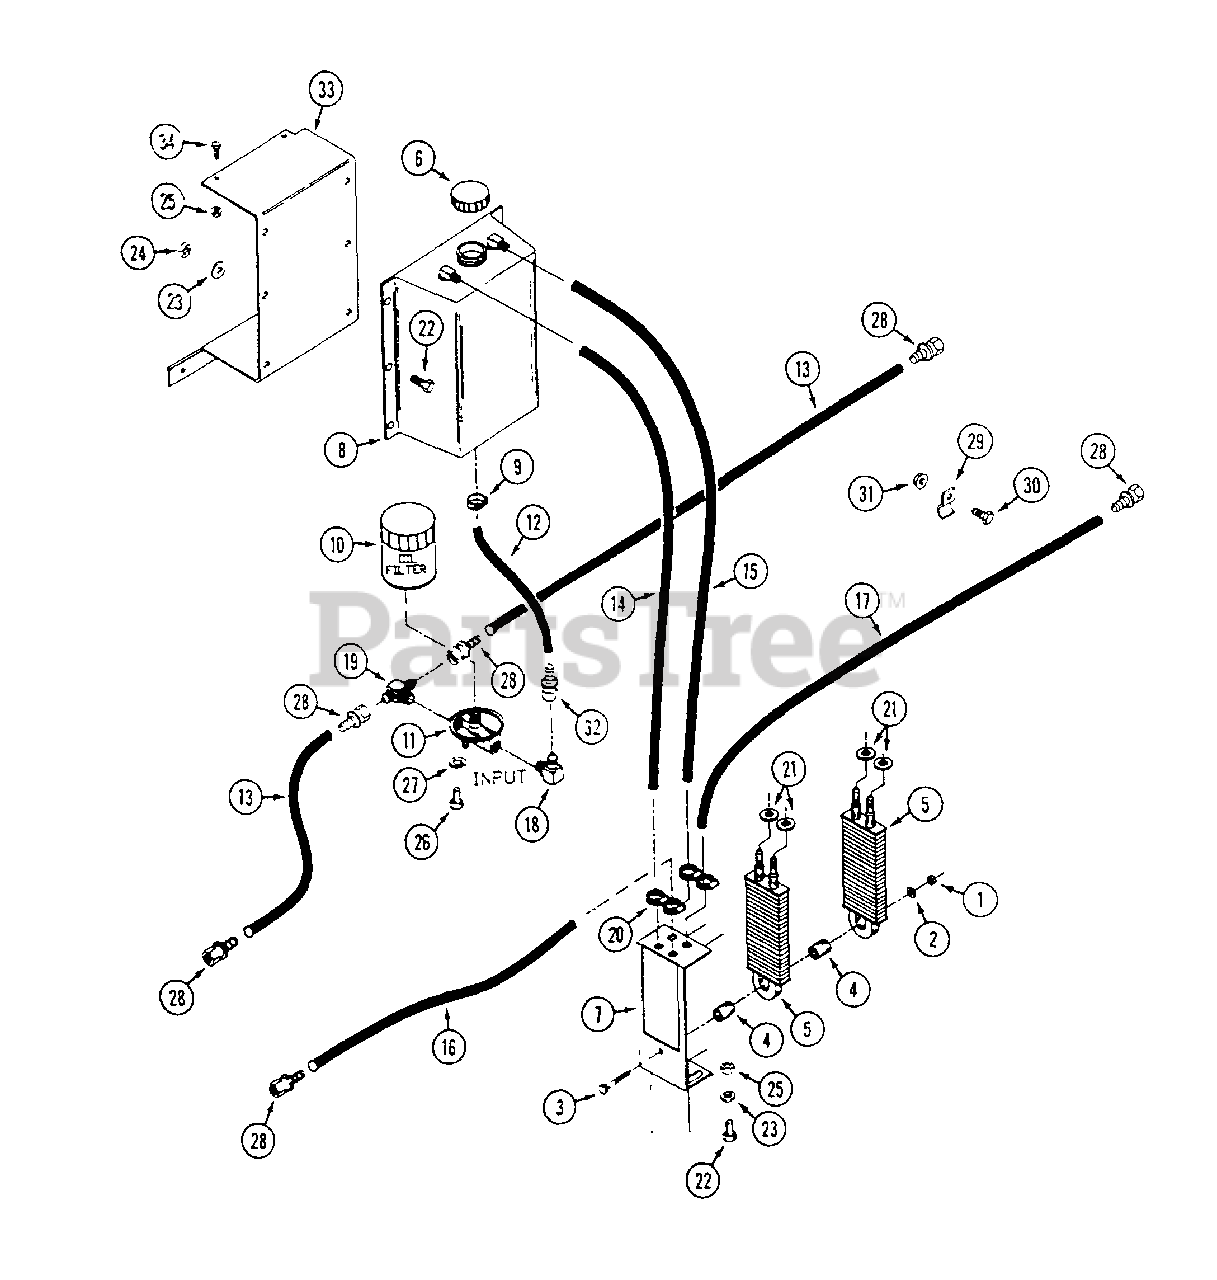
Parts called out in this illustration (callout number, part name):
1	NUT - lock 5/16"
2	WASHER - 5/16"
3	BOLT - 5/16" - 18 x 2-3/4"
4	BUSHING - rubber
6	CAP - oil tank
7	MOUNT - oil cooler
8	TANK - oil
9	CLAMP - hose 5/8"
10	FILTER - oil
11	HEAD - oil filter
12	HOSE - 5/8" x 11" (12" cut to length)
13	HOSE - hydraulic 3/8" x 13" (48" cut to length)
14	HOSE - hydraulic 3/8" x 25" (48" cut to length)
15	HOSE - hydraulic 3/8" x 27" (48" cut to length)
16	HOSE - hydraulic 3/8" x 38" (48" cut to length)
17	HOSE - hydraulic 3/8" x 24" (48" cut to length)
18	FITTING - male 90° adapter
19	FITTING - male tee adapter
20	CLAMP - hose 3/8"
21	GROMMET - 1/2" ID x 1" O.D.
22	BOLT - 1/4" - 20 x 3/4"
23	WASHER - 1/4"
24	NUT - 1/4" - 20 lock
25	NUT - 1/4" - 20 flange lock
26	BOLT - 1/4" - 20 x 3/4" self-tap
27	LOCKWASHER - 1/4"
28	FITTING - 3/8" hose barb x 3/8" FM JIG
29	CLIP - "J"
30	BOLT - 5/16" x 18 x 3/4"
31	NUT - 5/16" - 18 flange lock
32	FITTING - 5/8" hose barb x 1/2" FM JIC
33	MOUNT - oil tank
34	BOLT - 1/4" - 20 x 1/2"
